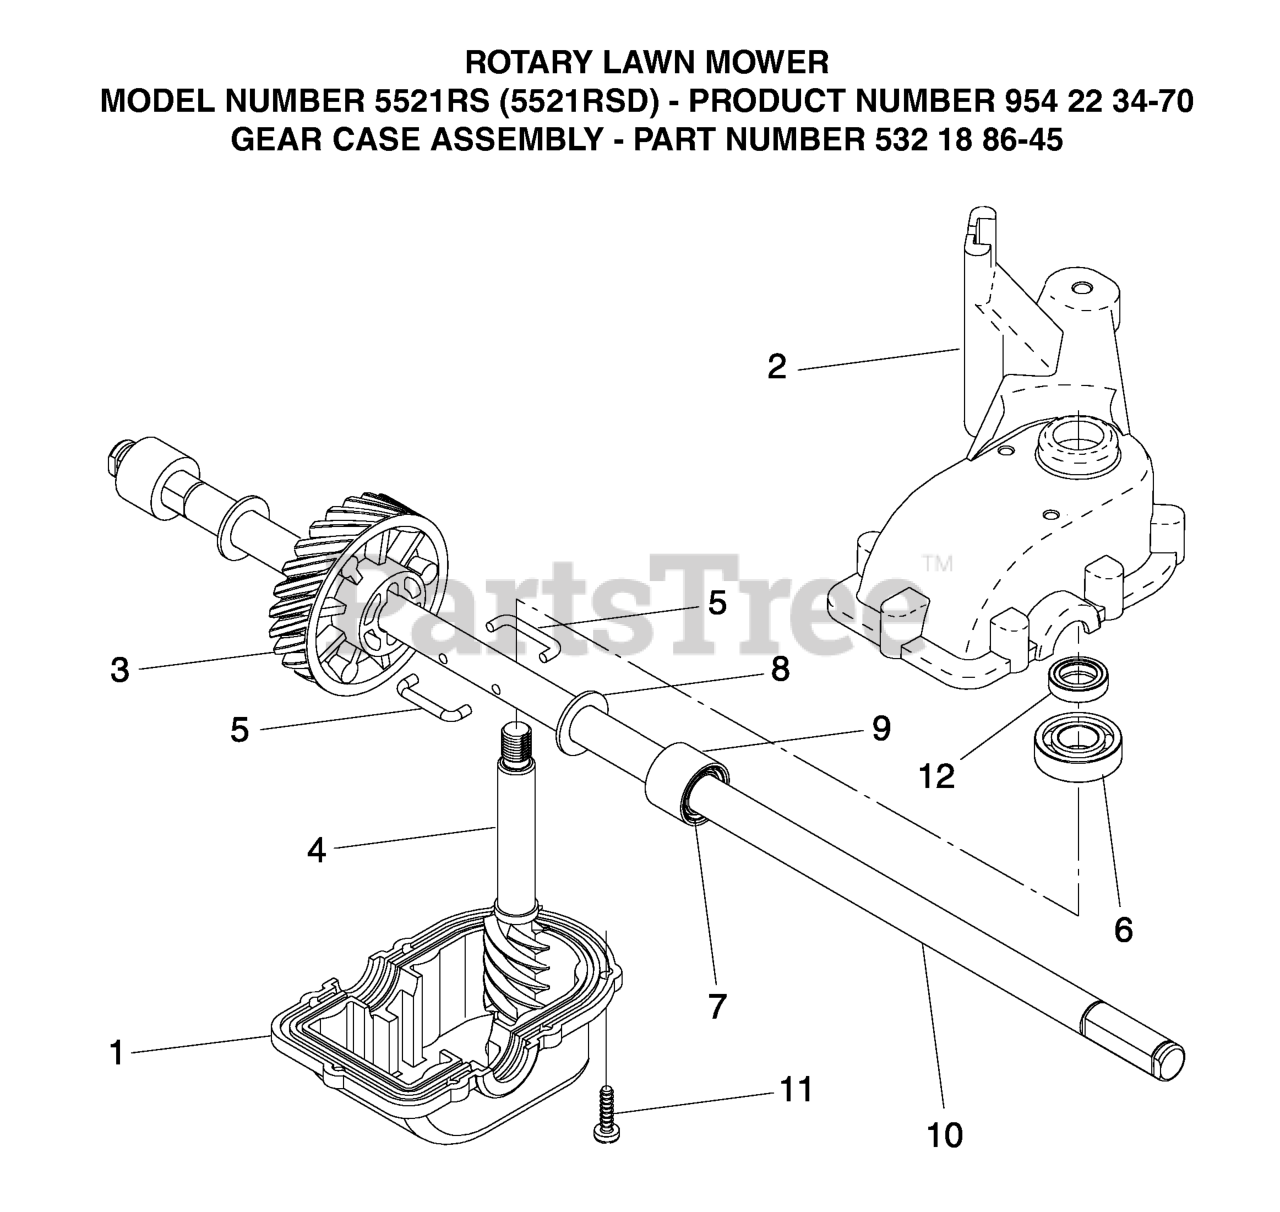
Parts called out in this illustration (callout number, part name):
1	CASE, LOWER
2	CASE, UPPER
3	GEAR.24.TOOTH.WALK.MOWER
4	SHAFT INPUT
5	RP.SHAFT.OUTPUT.RGD.VS/EZ
7	SEAL.OUTPUT.SHAFT
10	SHAFT OUTPUT (12215)
12	SEAL INPUT SHAFT
